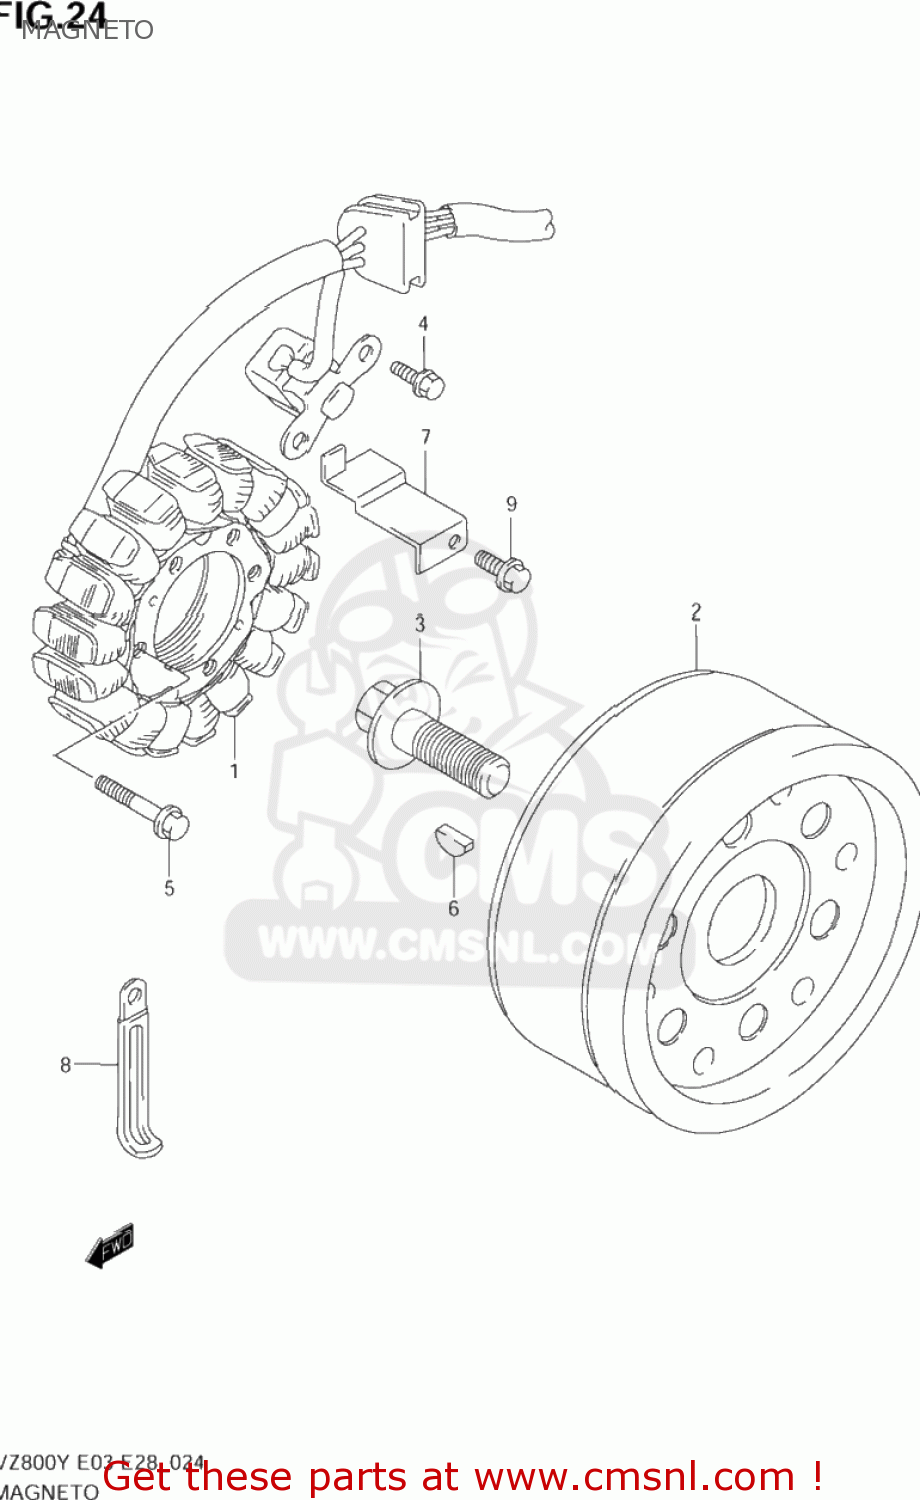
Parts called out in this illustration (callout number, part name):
1	STARTER ASSY
2	ROTOR ASSY
3	BOLT(14X43)
4	BOLT
5	BOLT,G/S SWITC
6	KEY
7	CLAMP,MAGNETO LEAD WIRE
8	CLAMP(L:65)
9	BOLT
